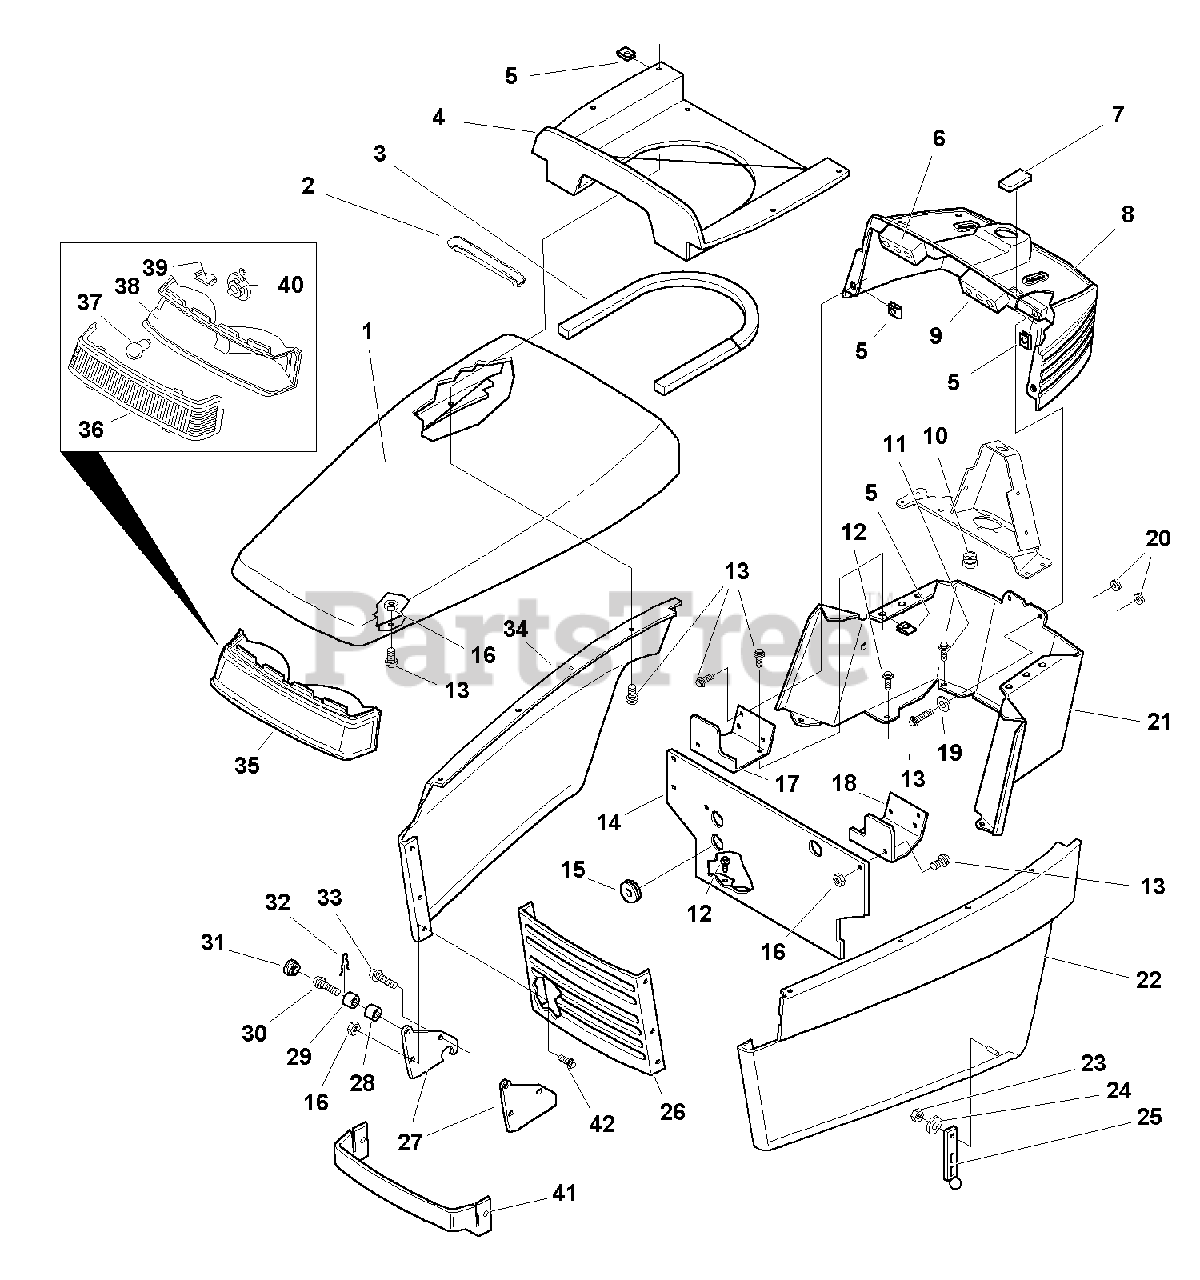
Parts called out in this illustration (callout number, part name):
1	HOOD, Red
1	HOOD, Orange
2	EDGING, 9" Long, Black Rubber
3	SEAL, Foam, 1.00 x 0.50 Horseshoe
4	DUCT, Air 16GA
5	NUT, Speed Lug
6	LENS, Indicator R H , (PTO On)
7	PLUG, Hole, Black Plastic
8	DASHBOARD, Lenses, (Includes Ref. Nos. 6 & 9)
9	LENS, Indicator L H, (BLUE/GREEN)
10	BUSHING, Nylon
11	CAPSCREW, Hex Washer Head, Taptite, 1/4-20 x 3/8
12	CAPSCREW, Hex Washer Head, Taptite, 1/4-20 x 1/2
13	CAPSCREW, Hex Flange Whizlock, 1/4-20 x 5/8
14	BULKHEAD
16	NUT, Hex Lock ESNA Light 1/4-20
17	SUPPORT, Bulkhead R H w/Hole
18	SUPPORT, Bulkhead L H
19	WASHER, 1/4
20	BUMPER, Button, Black Rubber
21	DASH, Lower 16GA
22	PANEL & WELD STUD ASSEMBLY, L H Side, Red
22	PANEL & WELD STUD ASSEMBLY, L H Side, Orange
23	NUT, Hex Lock, 10-24 w/Nylon Insert
24	WASHER, 3/16
25	STRAP, Hood, Black Rubber 4.8" Long
26	GRILLE, 16GA
27	HINGE, Hood
29	PIVOT, Hood
30	CAPSCREW, Hex Washer Head, Taptite, 5/16-18 x 1
31	SPACER, Nylon
32	PIN, Quick, (Hairpin)
33	CAPSCREW, Hex Wasker Head, Taptite, 5/16-18 x 5/8
34	PANEL & WELD STUD ASSEMBLY, R.H. Side, Orange
34	PANEL & WELD STUD ASSEMBLY, R.H. Side, Red
35	HEADLIGHT ASSEMBLY, (Includes Ref. Nos. 36, 37, 38, 39, & 40)
36	LENS, Headlight
37	BULB, Headlight
38	BEZEL, Headlight
39	HEAT SHEILD, Headlight
40	SOCKET, Headlight
42	CAPSCREW, Hex Flange Whizlock, 1/4-20 x 3/4
